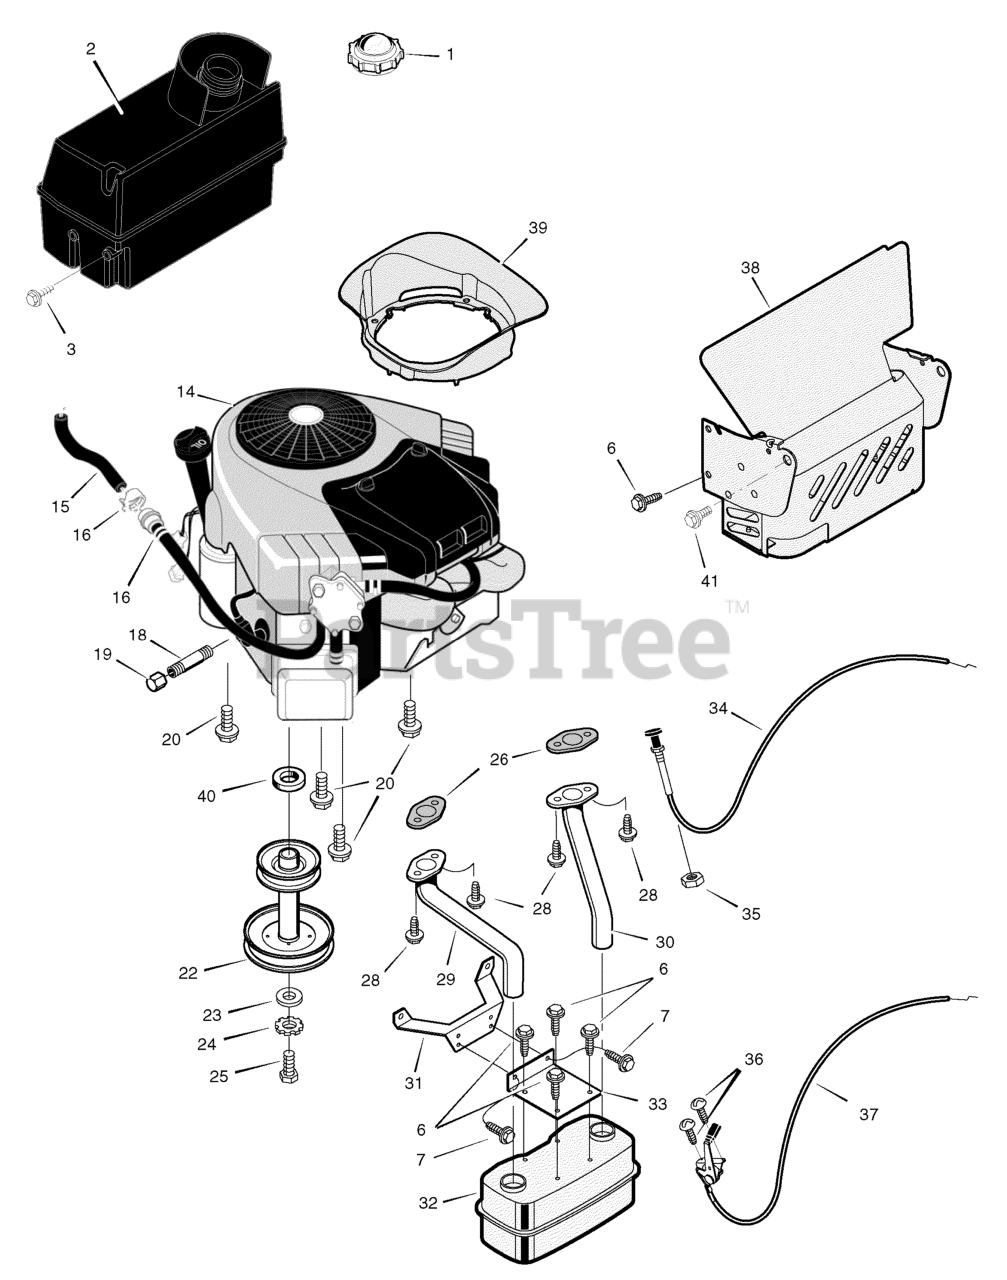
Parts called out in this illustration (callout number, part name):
1	Cap, Fuel
2	Tank, Fuel
6	Screw
7	Screw
14	Engine
15	Line, Fuel (Must cut to length)
16	Clamp, Hose
18	Pipe, Oil Drain
19	Cap, Oil Drain
20	Bolt
22	Pulley, Stack
23	Washer
24	Washer
25	Bolt
26	Gasket, Exhaust
28	Bolt
29	Tube, Right Exhaust
30	Tube, Left Exhaust
31	Bracket, Muffler Mount
32	Muffler
33	Bracket, Muffler
35	Nut
36	Screw
37	Control, Throttle
38	Shield, Heat
40	Spacer
41	Bolt
